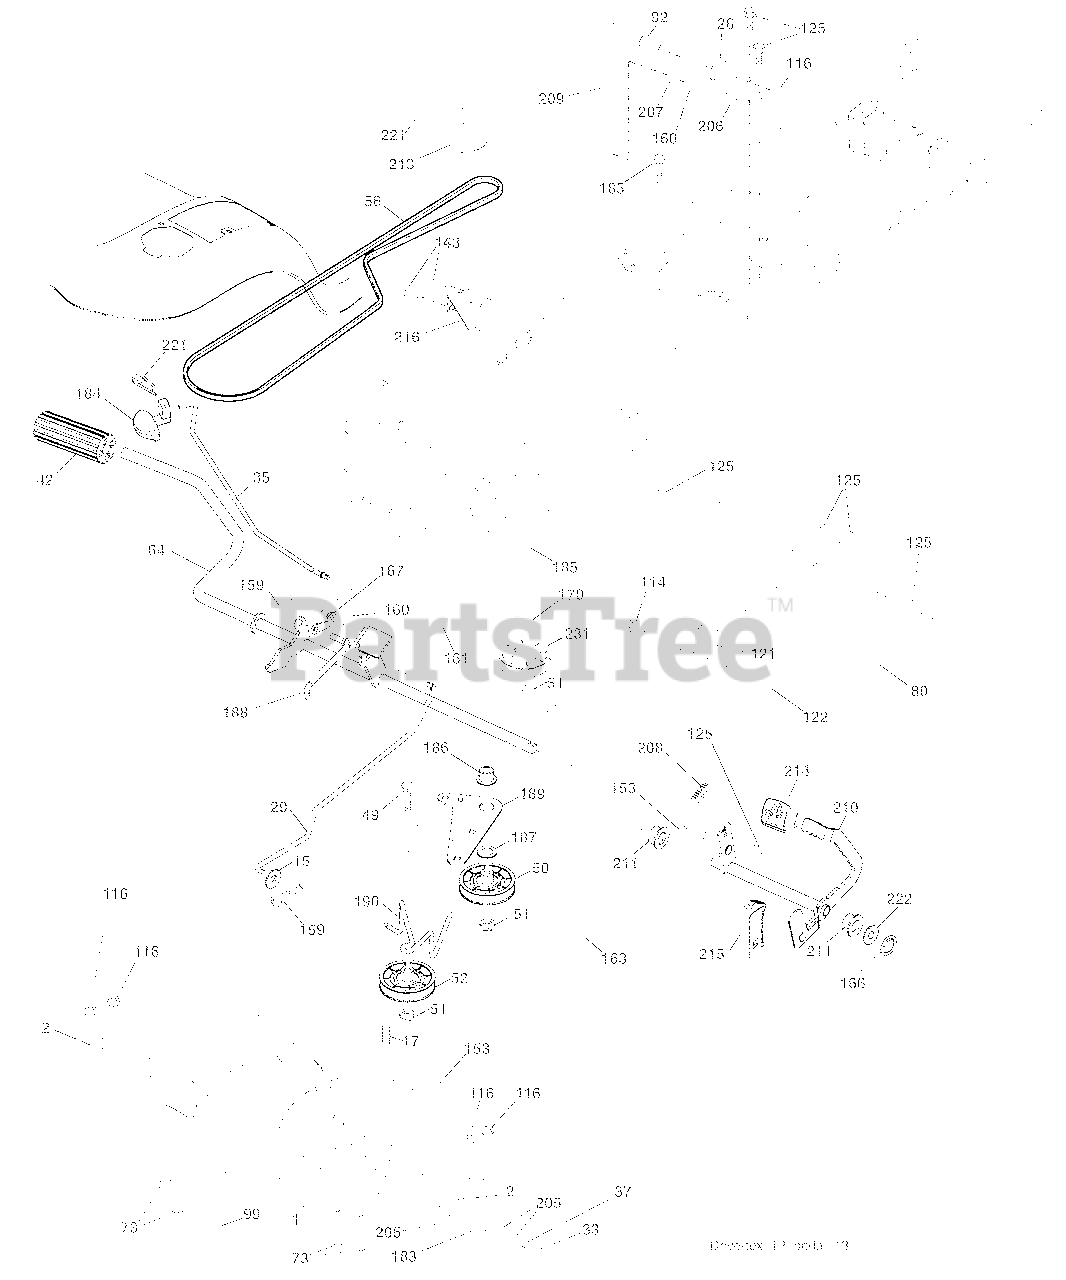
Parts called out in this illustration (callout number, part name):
15	Washer 13/32 x 13/16 x 16 Ga.
17	Spring, Brake
26	Spring Return Cruise
29	Rod, Brake
35	Rod, Brake, Park
37	Washer 25/32 x 1-1/4 x 16 Ga.
42	Cover, Foot Pedal
50	Pulley Idler Flat
51	Lock Nut 3/8-16
52	Idler V-Groove 910" Offset
56	V-Belt, Drive
64	Shaft Asm. Pedal Brake Control
73	Bolt 5/16-18 Gr. 5
80	Strap Torque
92	Bolt Fin Hex 5/16-18 unc x 1.25
99	Rod Asm Bypass Spring
114	Nut Lock 5/16-18 unc
116	Nut Lock Hex Flange 5/16-18
121	Bracket Strap Torque
122	Bolt 5/16-18 x 2.50
125	Screw 5/16-18 x 3/4
143	Screw THDROL 5/16-18 x 1/2
153	Retainer Spring
159	Pin Cotter 1/8 x 3/4
160	Retainer Clip
161	Spring, Return, Clutch
163	Rod Pedal Control
166	Nut Push .625
167	Latch Brake Parking
170	Keeper Belt Centerspan
183	Spacer Axle
184	Handle Parking Brake
186	Spacer Retainer
187	Washer
188	Link Clutch Ground Drive
189	Bellcrank Ground Drive
190	Keeper Bellcrank Ground Drive
205	Washer 25/32 x 1-5/8 x 16 Ga.
206	Bracket Mount Latch Cruise
207	Latch Control Cruise
208	Gear Sector Control Cruise
209	Rod Control Cruise
210	Rocker Asm. Pedal Control
211	Bearing Nylon
213	Knob Control Cruise
214	Pad Pedal Forward
215	Pad Pedal Reverse
216	Braket Pulley Idler
221	Retainer Spring Clip Handle
222	Washer 21/32 x 1-1/4 10 Ga.
231	Idler V-Groove 1.688
